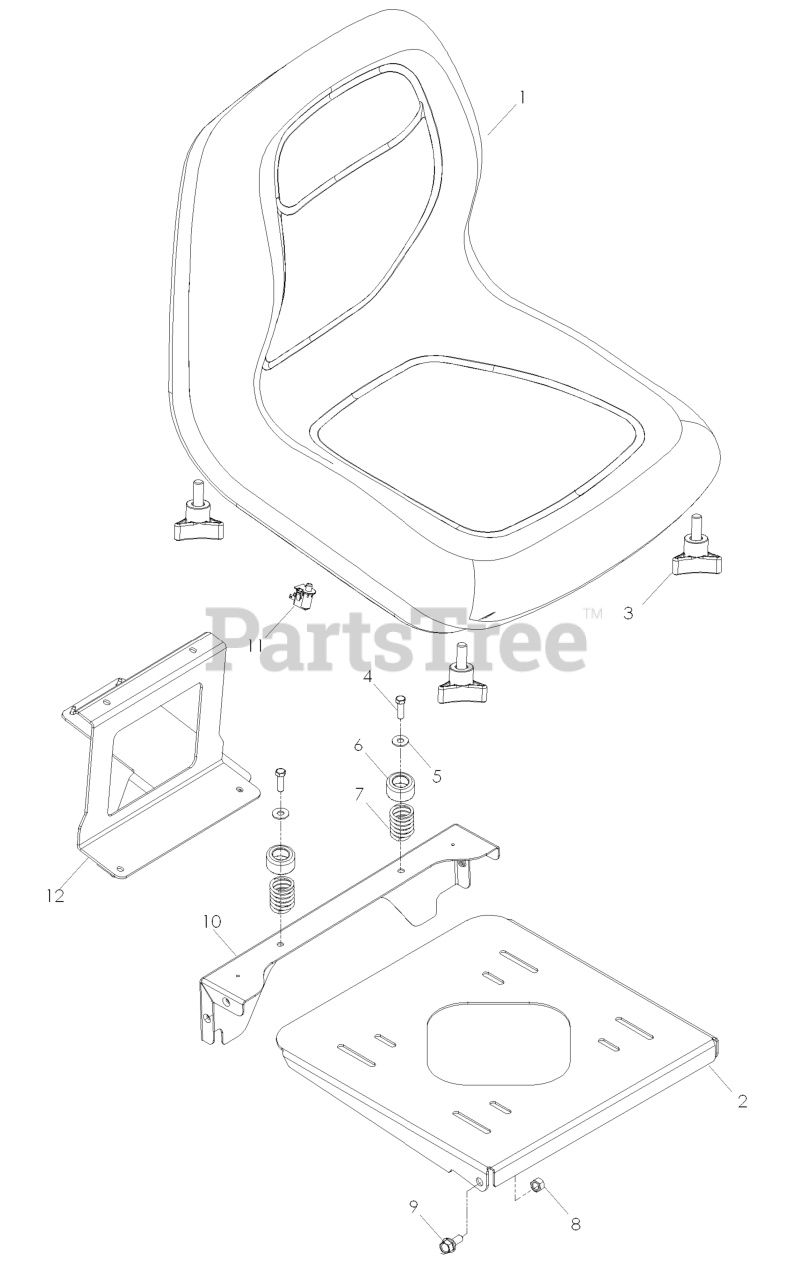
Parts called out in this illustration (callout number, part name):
1	SEAT.HIGHBACK.GREY.ZTR
1	SEAT.XH150.LOWBACK.GREY.ZTR
2	SEAT MOUNT, BLACK
3	KNOB W/STUD
4	BOLT, SHOULDER
5	WASHER 3/8 FLAT
6	CAP, SPRING COVER
7	SPRING, SEAT
8	NUT 5/16 NYLOC
9	HCS 3/8C X 1 1/4 GR5
10	REAR SEAT SUPPORT ORANGE
11	SEAT SWITCH
12	BRACKET, FRONT SUPPORT
